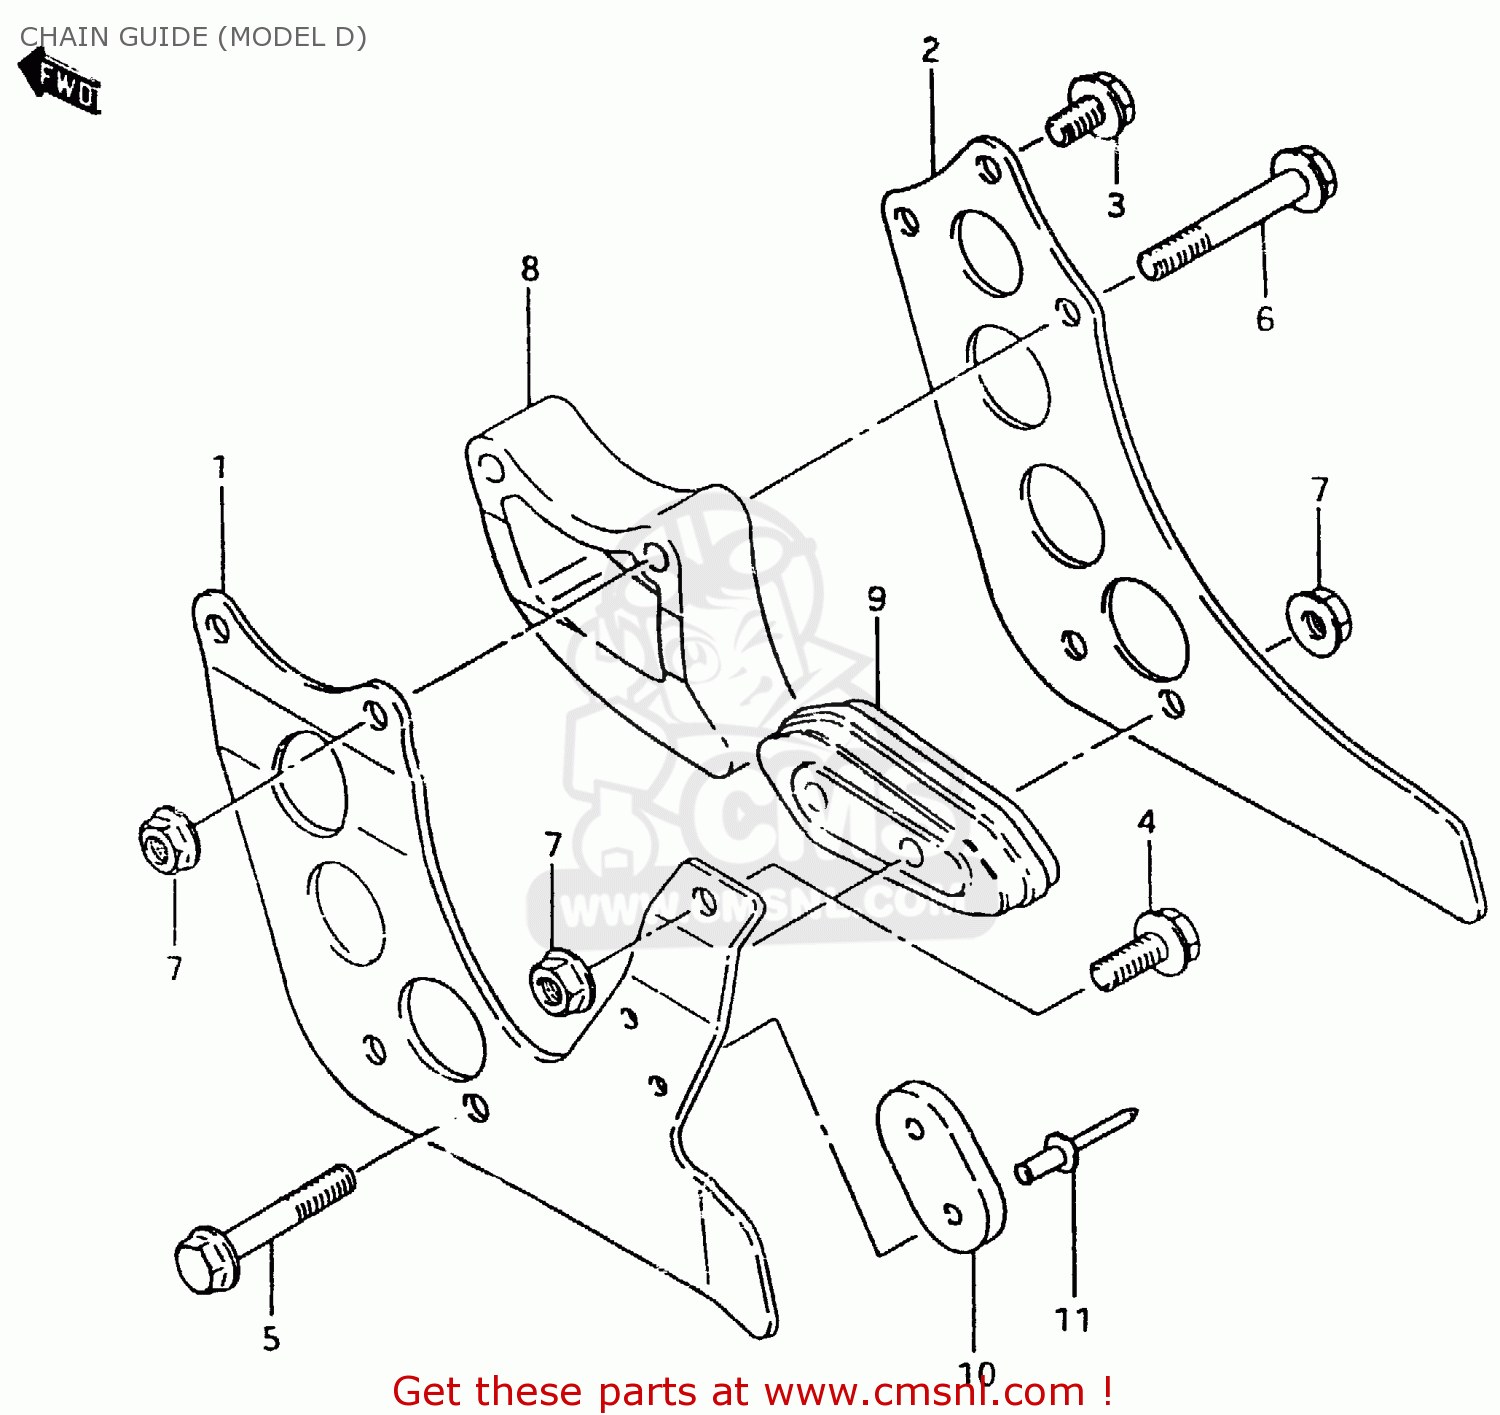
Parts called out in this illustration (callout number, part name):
1	PLATE,CHAIN GUIDE,OUTER
2	PLATE,GUIDE CHAIN
3	BOLT
4	BOLT
5	BOLT
6	BOLT,UNDER
7	NUT
8	DEFENSE,CHAIN GUIDE UPR
9	DEFENSE,CHAIN GUIDE
10	PAD,CHAIN GUIDE
11	RIVET
